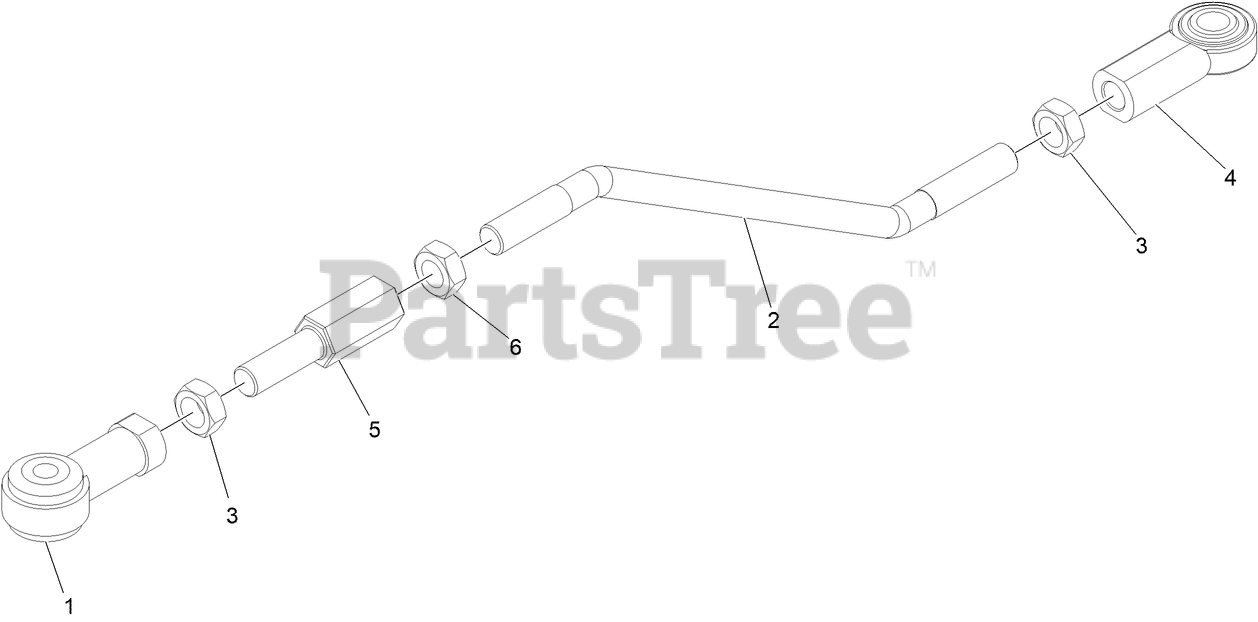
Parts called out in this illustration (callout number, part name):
1	ROD END - ISOLATED 1/2-20
2	ROD - LINKAGE
3	NUT-JAM
4	ROD END - 1/2-20
5	ROD - ADJUSTMENT
6	NUT-HEX JAM LH
